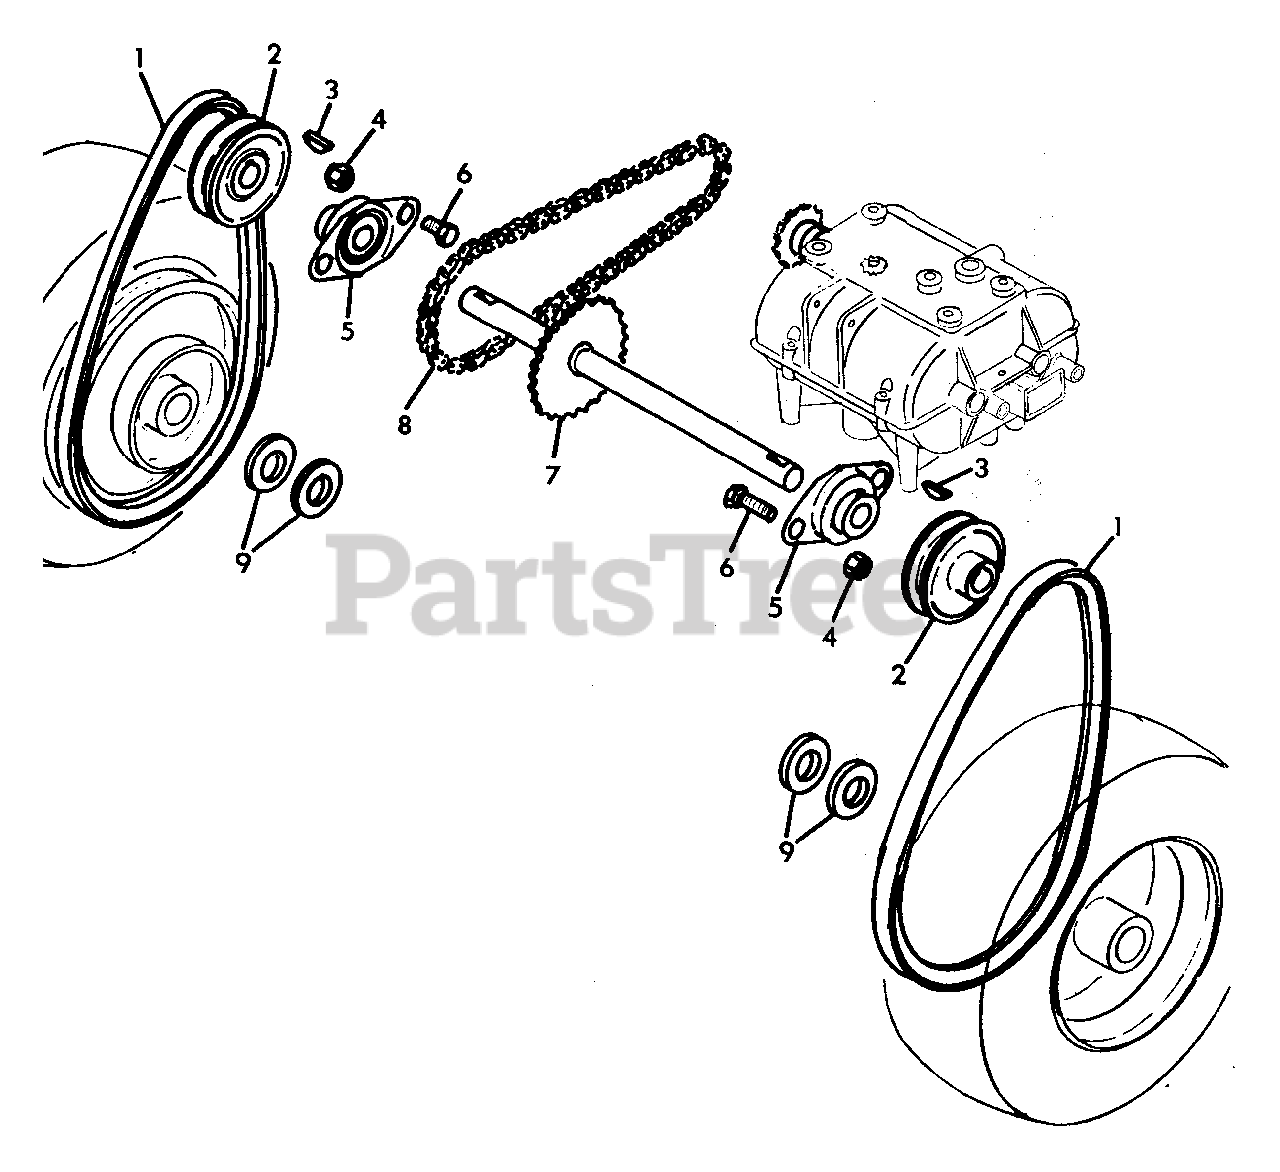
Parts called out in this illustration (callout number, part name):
1	Belt, Traction
2	Pulley, Jack-Shaft
3	Key, Woodruff 3/16x.750
4	Nut, Lock 3/8-16
5	Bearing
6	Bolt, Hex 3/8-16x.75
7	Weldment, Jack-Shaft
8	Chain, American Standard No. 40
9	Washer, Flat .938x1.750x.134
